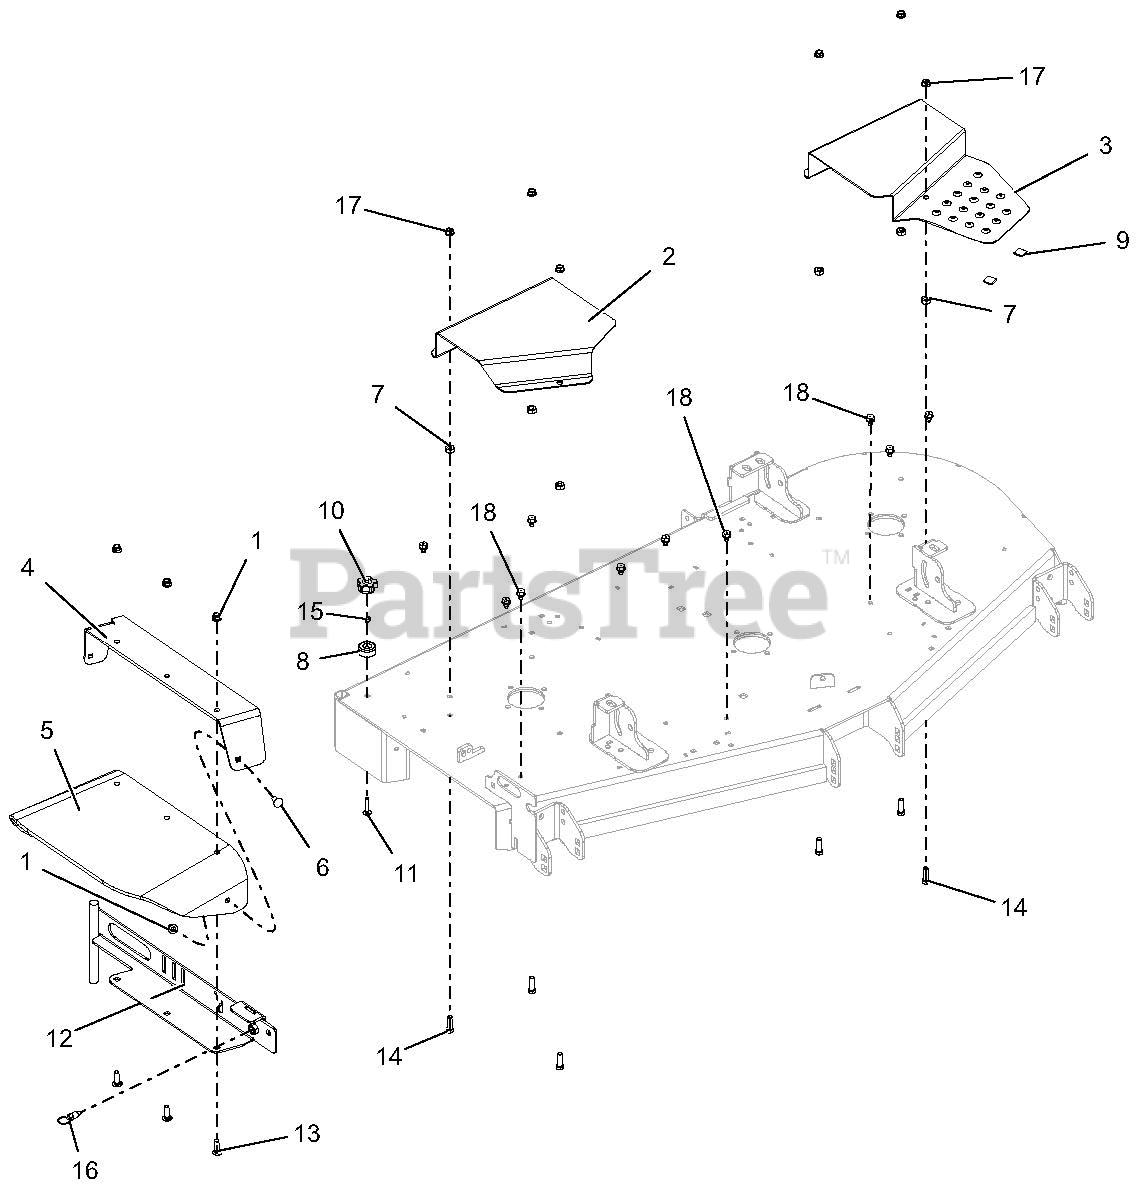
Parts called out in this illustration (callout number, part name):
1	NUT-LK-NYL-FLG .38-16 YWZC
2	GUARD, 60"-66" RH DECK BELT
3	GUARD, 60" LH DECK BELT-W/STEP
4	DISCHARGE CHUTE SUPPORT W/SAFETY DECAL
5	CHUTE, RUBBER DISCHARGE
6	BLT-RDHDSQNK .38-16X1.00 G5 YWZC
7	NUT-HEAVY HEX .38-16 YWZC
8	BUMPER, RECESSED 1.50 X .63 W/.31 HOLE
10	KNOB, CLAMPING
11	BLT-RDHDSQNK .31-18X1.50 G5 YWZC
12	WLDMT, 52"-60" DISCH CHUTE MTG
13	BLT-RDHDSQNK .38-16X1.25 G5 YWZC
14	BLT-HEX .38-16X1.25 GR5 YWZC
15	NUT-LK-CTR .31-18 YWZC
16	PULL PIN,.50-13THDX.310 PLNGR
17	@NUT-SPNLK-FLG .375-16 YWZC
18	SCR-TAP .38-16X.50 HWH TR YWZ
